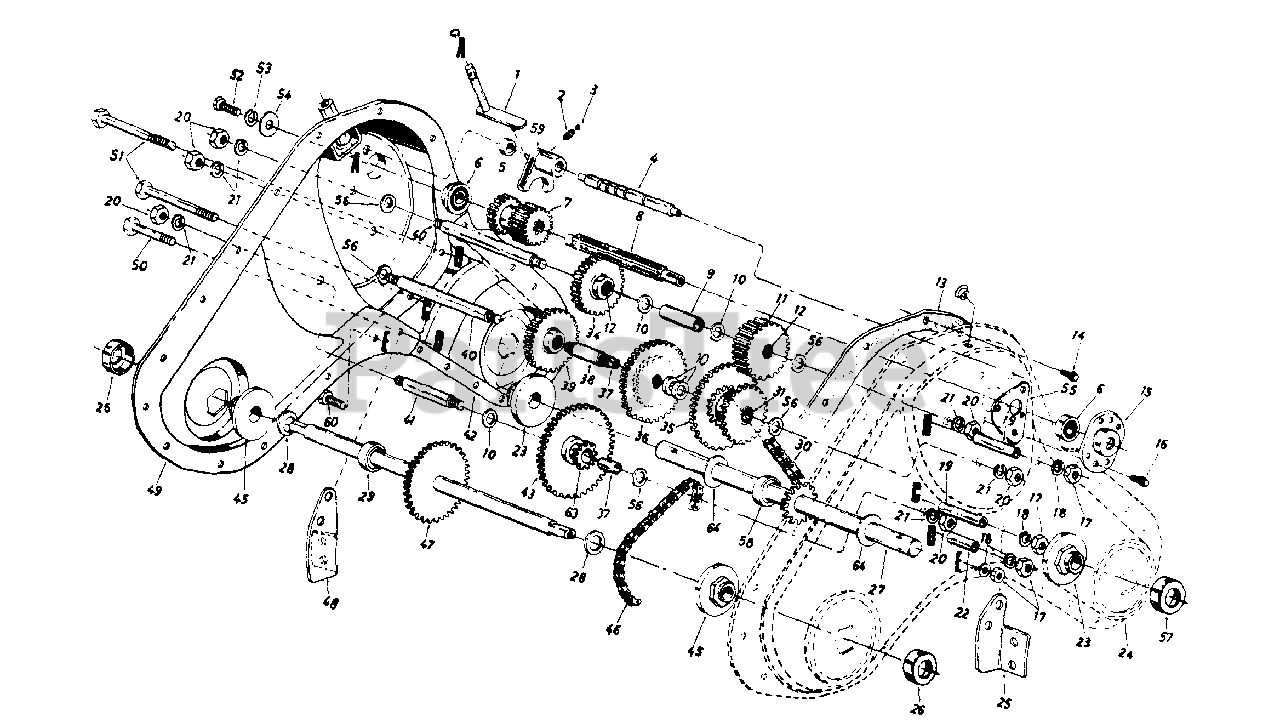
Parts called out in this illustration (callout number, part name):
1	Shifting Bracket Ass'y.
2	Compression Spring .50" Lg.
3	Ball Detent .250" Dia.
4	Detent Shaft 1/2" Dia.
5	Spacer .505" I.O. x .88" O.D.
6	Ball Brg..62" I.O. x 1.38"
7	Spur Gear 16T (Input)
8	Input Spline Shaft 7/8"
9	Spacer .657" I.D. x 2.85" Lg.
10	Fl-Wash..640" I.D. x 1.24"
11	Spur Gear 30T 7/8" I.D.
12	Needle Bearing 5/8" I.D.
13	Gasket - Trans. Hsg.
14	Hex S-Tap Scr. 1/4-20 x .5"
15	1-3/8" Dia. Bearing Housing
16	Hex TT-Tap Scr. 1/4-20 x .75"
17	Hex Nut 5/16-18 Thd.
18	L-Wash. 5/16" I.D.
19	Spacer 1.56" Lg.
20	Hex Nut 7/16-20 Thd.
21	Bell-Wash..45" I.D. x 1.0"
22	Spacer 1.015" Lg.
23	Tine Shaft Brg. 1.002 x 2.50
24	Trans. Housing Ass'y.- L.H.
27	Tine Shaft Ass'y. 1" O.D.
28	Fl-Wash..76" I.D. x 1.5" O.D.
29	Spacer .75" I.D. x .50" Lg.
30	Chain #50 5/8 Pitch x 52 Links - Endless
31	Needle Bearing 5/8" I.D.
34	Spur Gear 30T 12/16" I.D.
35	30/44T Gear Ass'y. Comp.
36	Spur Gear 44T
37	Sleeve Bearing
38	Gear Hub 3/4" I.D. x 3" Lg.
39	Spur Gear 30T 1.0" I.D. x 1/2" W
40	Jack Shaft 5/8" Dia. x 5"
41	Jack Shaft 4/8" x 2.38"
45	Wheel Brg. .752" x 2.5"
46	#420 Chain 1/2 Pitch x 50 Links - Endless
47	Wheel Shaft Ass'y. 15.6"
51	Hex Bolt 5/16-18 x 2.5
52	Hex Bolt 1/4-20 x 62" Lg.
53	L-Wash. 3/8" I.D.
54	Fl-Wash. 1/4" I.D. x .93" O.D.
55	Gear Positioner Bracket
56	Fl-Wash. T/16" I.D. x 1-3/8"
57	Dust Cover Ass'y. 1" Shaft
58	Spacer 1" I.D. x 2" O.D.
59	Shifting Fork
60	Hex Bolt 5/16-18
63	10T Sprocket Ass'y.
64	Thrust Wash. 1.03" I.D. x 1.62" O.D.
